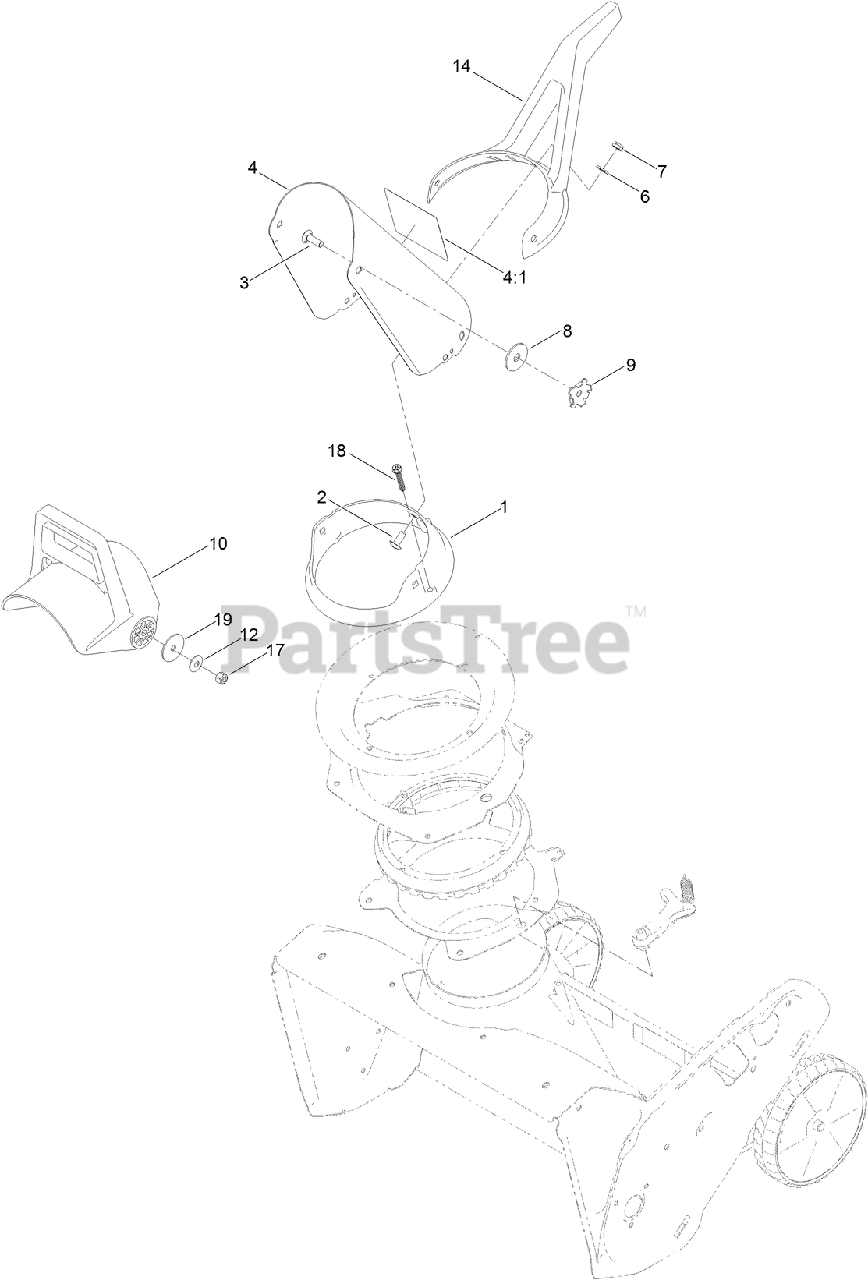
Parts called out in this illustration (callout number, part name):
1	RING-CHUTE
2	SCREW-PTH
3	SCREW-CARR
4	DISCHARGE CHUTE ASM
4:1	DECAL-DANGER, CE
6	WASHER-FLAT
7	NUT-LOCK, NI
8	WASHER-RUBBER
9	PLATE-FRICTION
10	CHUTE-DEFLECTOR
12	WASHER-BELLEVILLE
14	HANDLE-CONTROL, CHUTE
17	NUT-HEX
18	SCREW-PLASTITE
19	WASHER-FLAT
